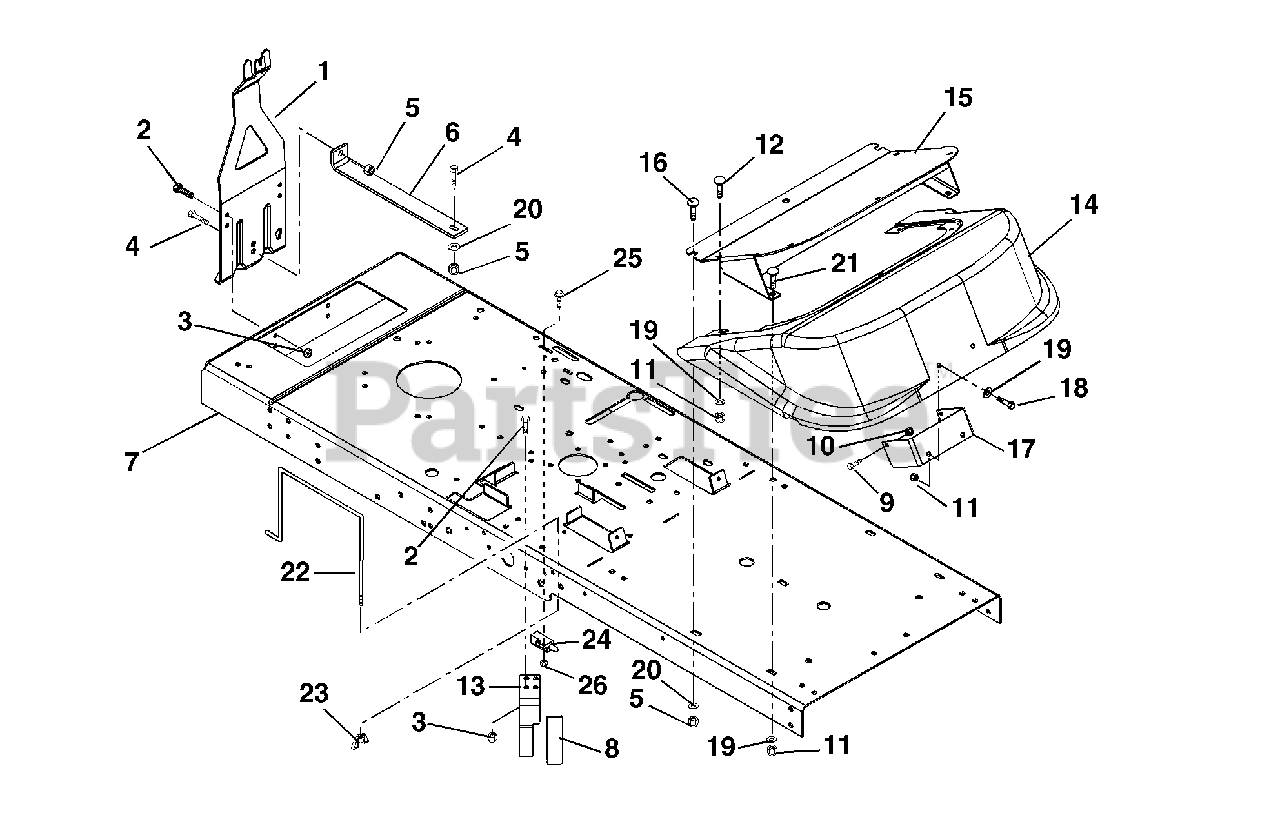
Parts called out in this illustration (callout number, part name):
1	HITCH, TRAILER
1	BRACKET, TRAILER HITCH
2	@BLT-HEX .31-18X.75 GR5 YWZC
3	@NUT-LK-CTR .31-18 YWZC
4	@BLT-HEX .38-16X1.00 GR5 YWZC
5	@NUT-LK-CTR .38-16 YWZC
9	@BLT-HEX .25-20X.75 GR5 YWZC
10	@NUT-LK-NYL .250-20 YWZC
10	@NUT-LK-CTR .25-20 YWZC
11	@NUT-LK-NYL .312-18 YWZC
12	@BLT-RHDSSQNK .31-18X.75 G5YZ
13	STOP - CLUTCH
14	SHROUD, FOOTREST
15	FOOTREST, WLDM'T
15	FOOTREST
16	@BLT-RDHDSQNK .38-16X.75 G5YZ
17	BRACKET, FOOTREST
17	BRACKET - FOOTREST
18	@BLT-HEX .31-18X.75 GR5 YWZC
18	@BLT-RDHDSQNK .25-20X.50 G5YZ
19	@WSHR-FL-STL.38X.875X.083 YWZC
20	@WSHR-FL-STL.406X.812X.065 YWZ
21	@BLT-RDHDSQNK .31-18X1.00 G5YZ
22	BATTERY ROD
23	NUT-LK WING .250-20 YWZC
24	SWITCH- SINGLE POLE N.O.
25	BLT-HEX FWH #10X.750 YWZC
26	@NUT-LK-NYL 10-24 W/INSRT YWZC
